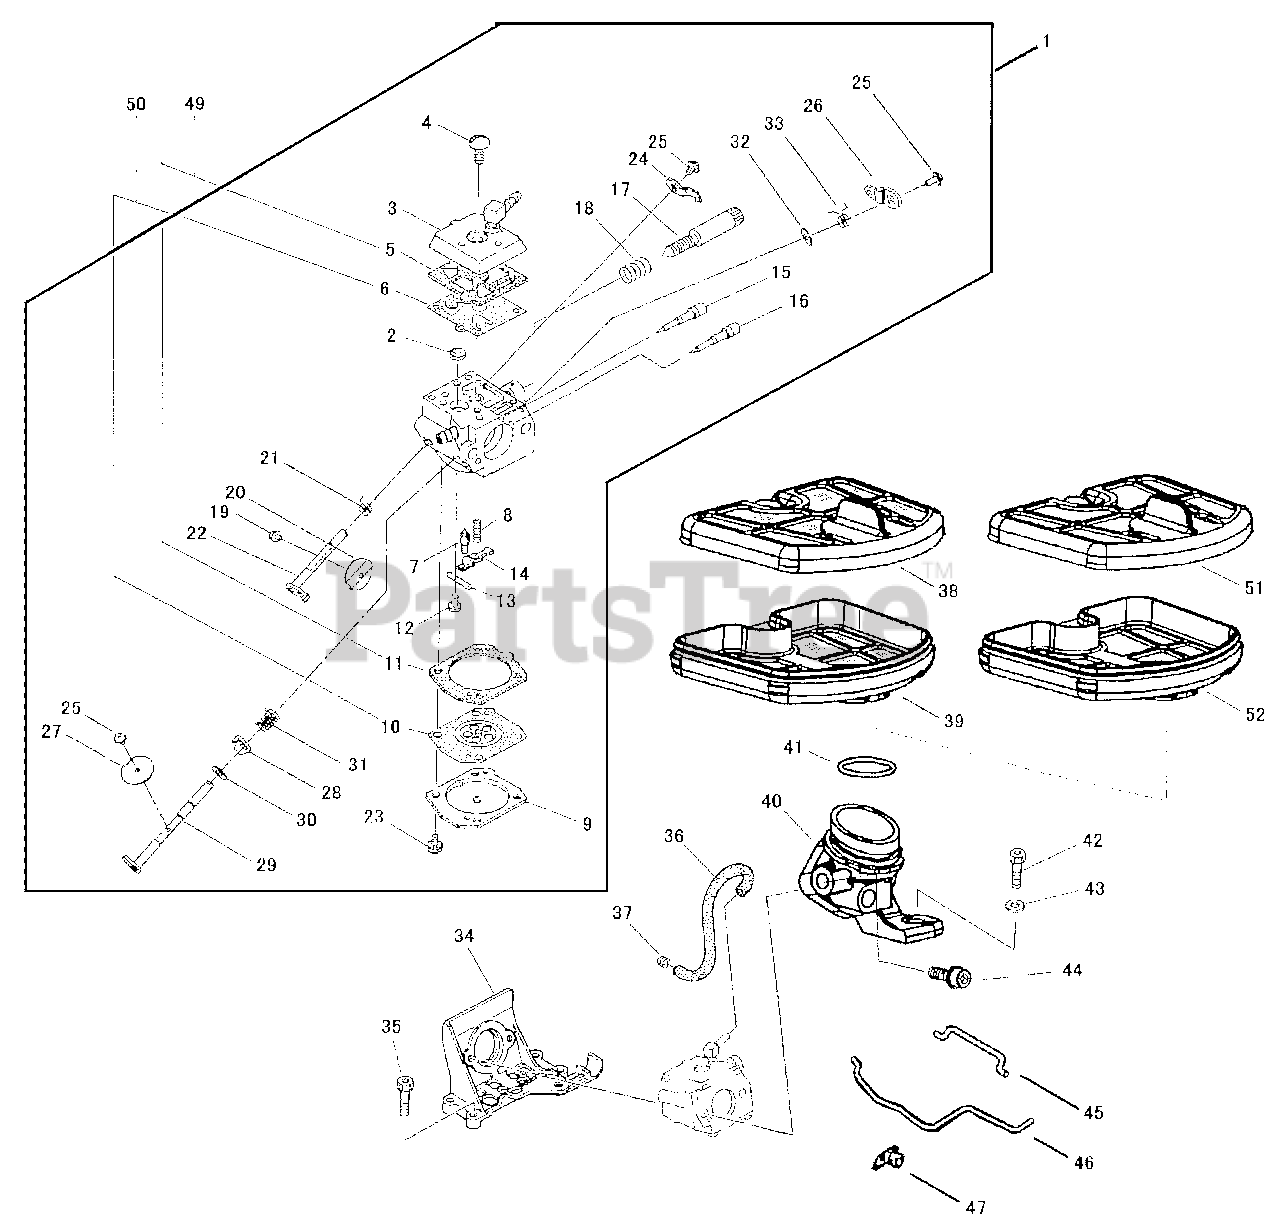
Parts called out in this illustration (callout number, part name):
1	CARBURETOR
2	STRAINER
3	COVER, PUMP
4	SCREW, PUMP COVER
5	GASKET, PUMP
6	DIAPHRAGM, PUMP
7	VALVE, INLET NEEDLE
8	SPRING, METERING LEVER
9	COVER, DIAPHRAGM
10	DIAPHRAGM, METERING
11	GASKET, METERING
12	SCREW, METERING LEVER PIN
13	PIN, METERING LEVER
14	LEVER, METERING
15	VALVE, NEEDLE
16	VALVE, NEEDLE
17	SCREW, IDLE ADJUST
18	SPRING
19	SCREW
20	VALVE, THROTTLE
21	SPRING, THROTTLE RETURN
23	SCREW
24	STOP, THROTTLE
25	SCREW
27	VALVE, CHOKE
29	SHAFT
30	WASHER
32	RING, RETAINING
34	MOUNT
35	SCREW - 4X16
36	PULSE TUBE
37	CLIP
38	FILTER, AIR - UPPER -- NYLON
39	FILTER, AIR - LOWER -- NYLON
42	BOLT - 5X18
43	WASHER - 5
44	SCREW - 5X50
45	ROD, CHOKE
46	ROD, THROTTLE
47	GROMMET
49	GASKET KIT
50	DIAPHRAGM KIT
51	FILTER, AIR - UPPER -- FLOCKED
52	FILTER, AIR - LOWER -- FLOCKED
